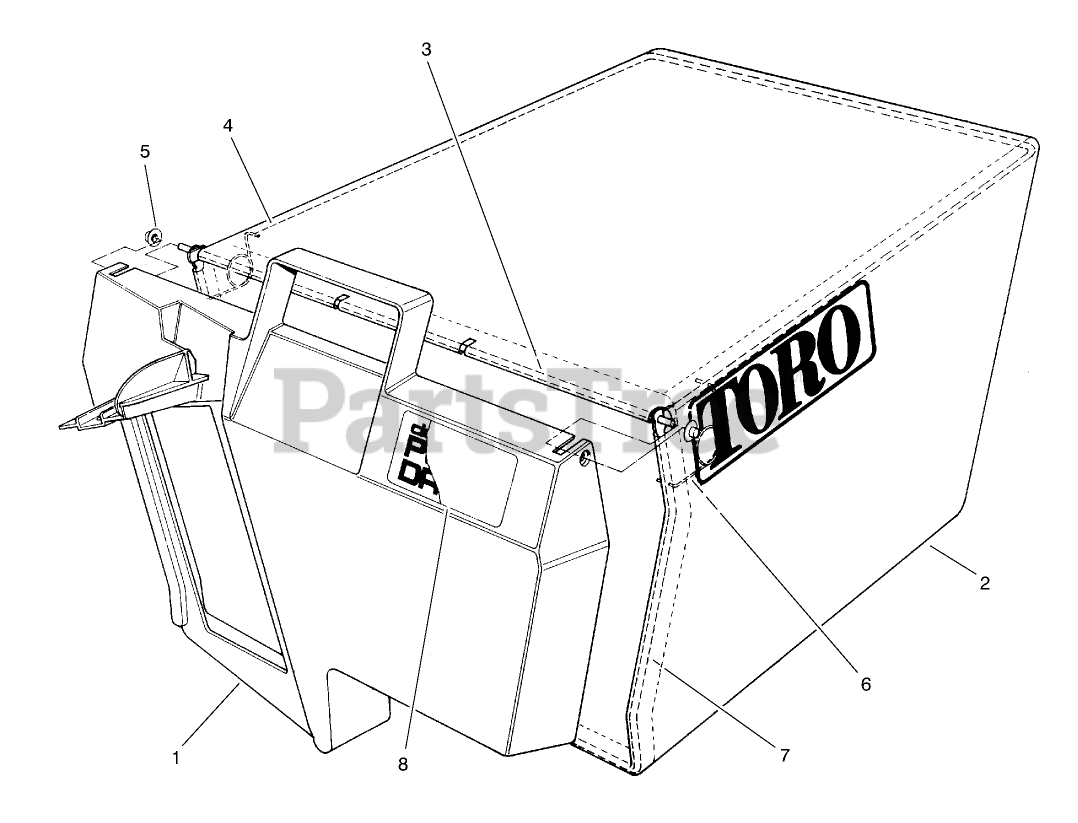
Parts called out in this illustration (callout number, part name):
1	DOOR-BAG
2	Bag
3	HINGE-DOOR, BAG
4	FRAME-BAG, UPPER
5	NUT-PUSH
6	SPRING
7	FRAME-BAG
8	BAG DOOR DECAL
